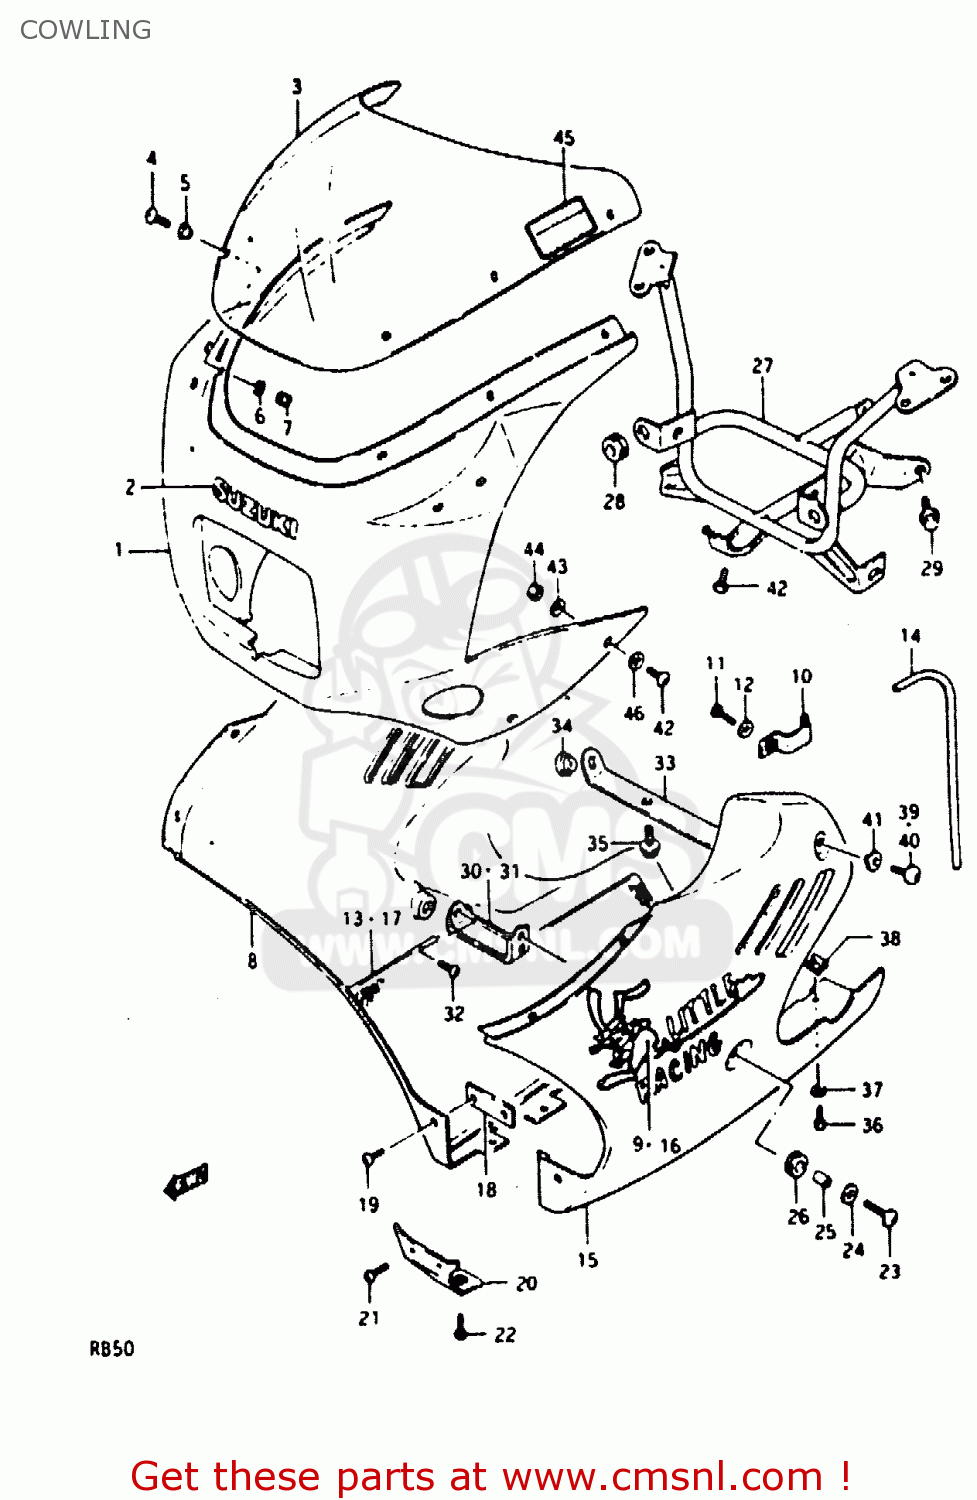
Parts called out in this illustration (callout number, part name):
1	BODY,COWLING
2	EMBLEM
3	WINDOW,COWLING
4	SCREW
5	CUSHION
6	WASHER,5MM
7	NUT 8MM
8	COVER SET,COWLING,R
10	CLAMP
11	SCREW
12	WASHER
13	SHIELD,UNDER COWL HEAT,R
14	HOSE
15	COVER SET,COWLING,L
18	BRACKET,COWLING LWR
19	SCREW
20	BRACKET,COWLING LWR
21	SCREW
22	SCREW
23	SCREW
24	WASHER(6.5X18X1)
25	SPACER (6.1X9X9)
26	CUSHION
27	BRACE,COWLING
28	CUSHION
29	BOLT
30	BRACE,COWLING LWR,R
31	BRACE,COWLING,LOWER,LEFT
32	SCREW
33	PLATE,COWLING SUPPORT
34	CUSHION
35	BOLT
36	SCREW
37	WASHER(5.2X16X1)
38	NUT
39	SCREW 6X12
40	SCREW(6X16)
41	WASHER
42	SCREW
43	WASHER
44	NUT
46	WASHER
